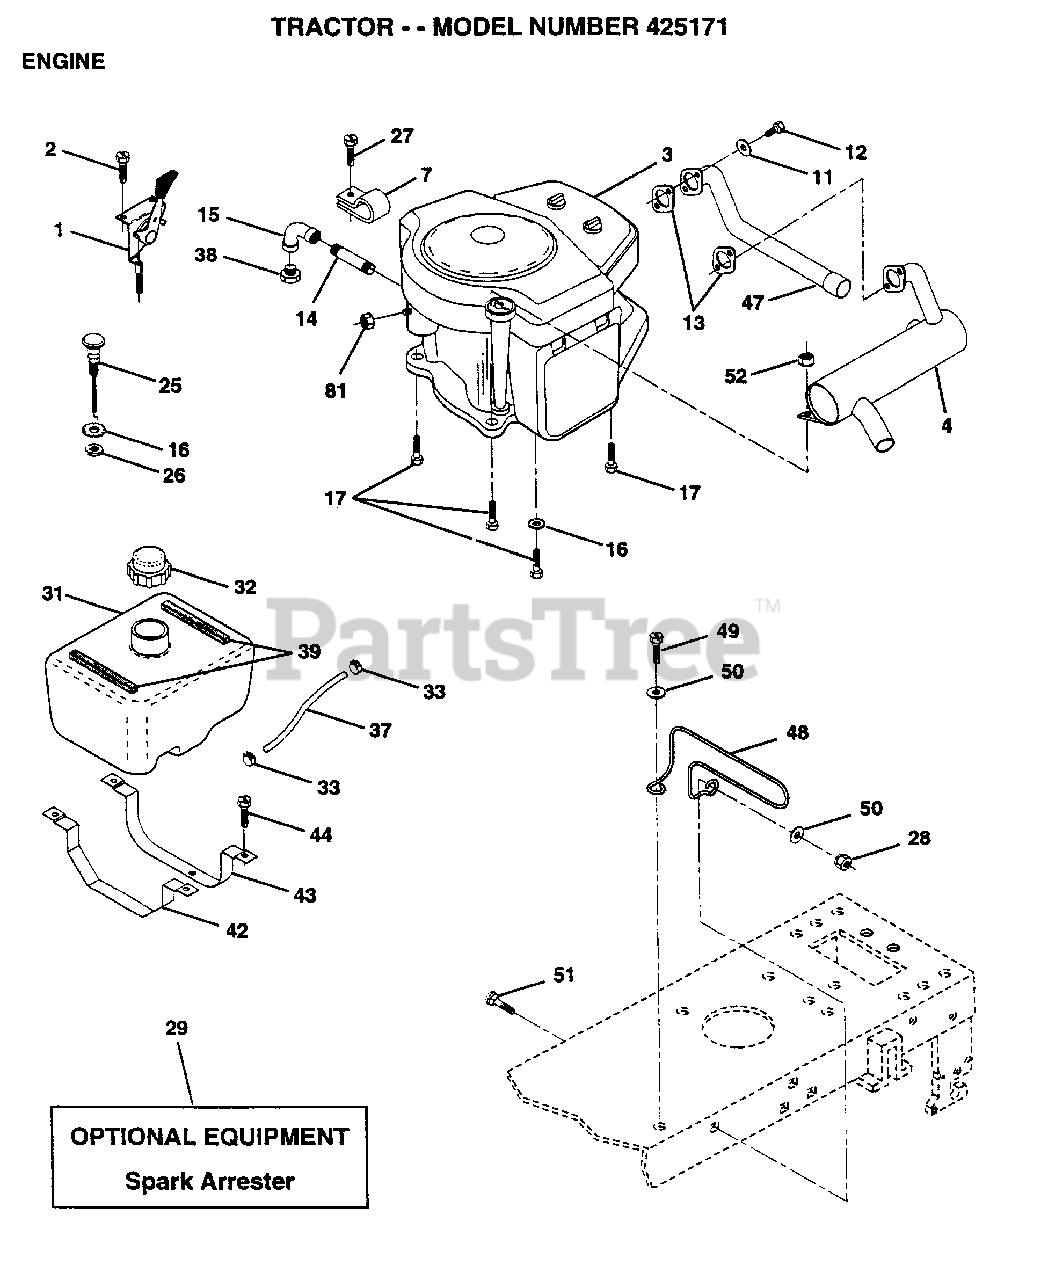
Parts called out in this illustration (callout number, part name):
2	SCREW LT
3	ENGINE B&S 18HP
7	CLAMP.TUBE.DBL.EN
11	LOCKWASHER
14	PIPE NIPPLE LT
15	ELBOW
16	LOCKWASHER
17	SCREW LT
25	"CONTROL.CHOKE.51"""
27	SCREW.10-24X1/2
31	TANK FUEL 1.9 NAT
32	CAP ASM FUEL
33	HOSE CLAMP
37	HOSE T
39	"STRIP,FORM"
42	STRAP TANK FUEL
43	STRAP TANK FRONT
44	SCREW
47	EXHAUST TUBE T
48	MUFFLER GUARD
49	SCREW
50	WASHER HYT
51	BOLT D
52	NUT
81	NUT
